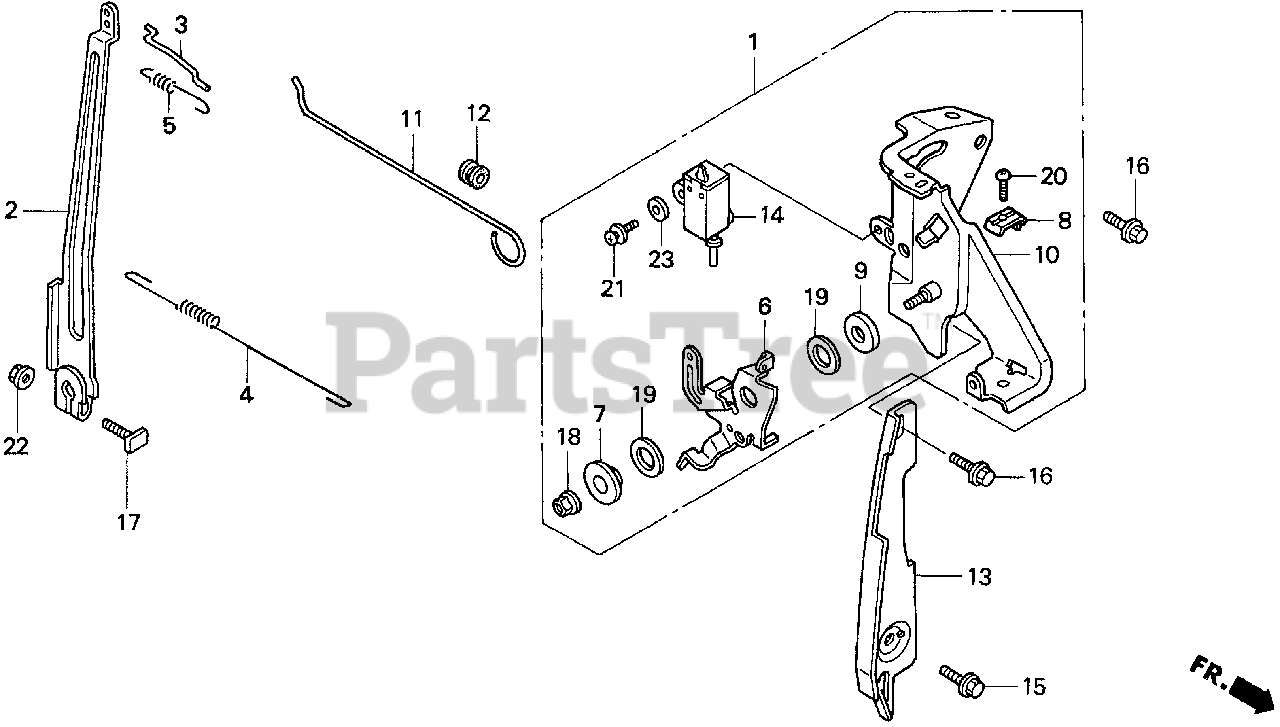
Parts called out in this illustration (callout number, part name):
1	CONTROL ASSY.
2	ARM, GOVERNOR
3	ROD, GOVERNOR
4	SPRING, GOVERNOR
5	SPRING, THROTTLE RETURN
6	LEVER, CONTROL
7	WASHER, CONTROL LEVER
8	HOLDER, CABLE
9	SPACER, CONTROL LEVER
10	BASE, CONTROL
11	ROD, CHOKE CONTROL
12	GROMMET, CHOKE ROD
13	PLATE, SIDE
14	SWITCH ASSY., ENGINE STOP (N.O)
15	BOLT, FLANGE (6X12) (CT200)
16	BOLT, FLANGE (6X14)
17	BOLT, GOVERNOR ARM
18	NUT, SELF-LOCK (6MM)
19	WASHER (12.5MM)
20	SCREW, PAN (5X16)
21	SCREW-WASHER (4X12)
22	NUT, FLANGE (6MM)
23	WASHER, PLAIN (4MM)
